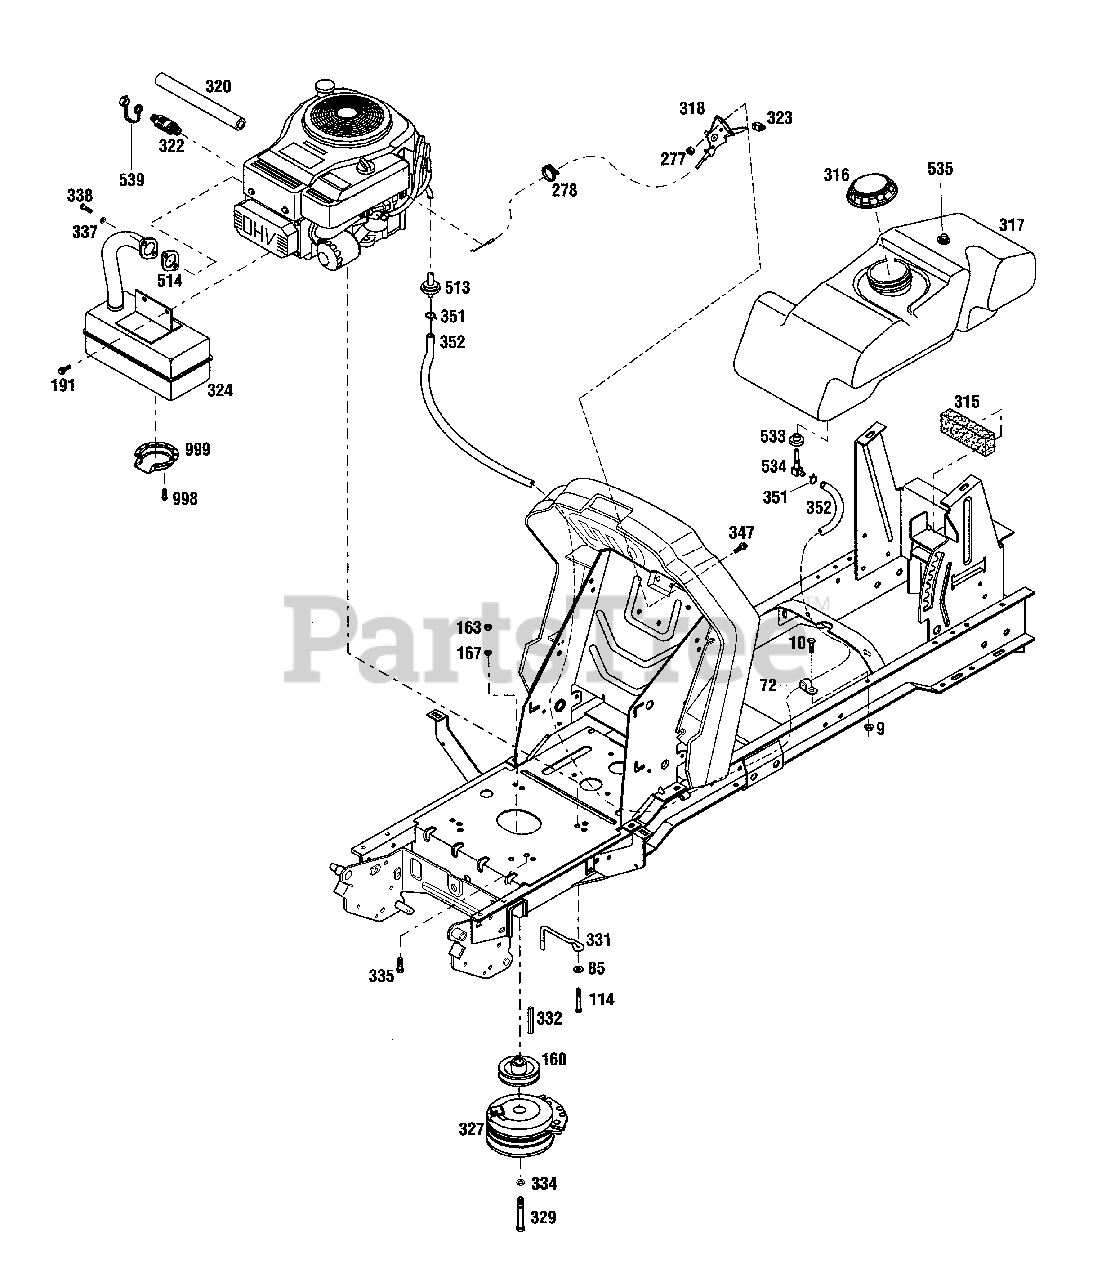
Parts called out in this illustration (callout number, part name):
9	Flange Nut, 5/16-18
10	Hex Head Screw, 5/16-18 x 3/4
85	Flat Washer, 3/8
114	Hex Head Screw, 3/8-16 x 1-1/2
160	Engine Sheave
163	Hex Nut, 3/8-16
167	Lockwasher 3/8
191	Flange Screw, 1/4-20 x 3/4
277	Keps Locknut, 10-24
278	Cable Tie
315	Fuel Tank Pad
316	Fuel Cap
317	Fuel Tank (Incl. Refs. 533, 534 & 535)
318	Throttle Choke Control (NLA)
320	Oil Drain Hose
322	Oil Valve Assembly (Incl. Ref. 539)
323	Control Knob
324	Muffler (Single Inlet)
327	Electric Clutch
329	Hex Head Screw, 7/16-20 x 3-1/4
331	Clutch Retainer
332	Square Key, 1/4 x 1-1/2
334	Spring Lock Washer, 7/16
335	Hex Head Screw, 3/8-16 x 1
337	Lock Washer, 5/16
338	Socket Cap Screw, 5/16-18 x 5/8
347	Machine Screw, 10-24 x 3/4
351	Hose Clamp
352	Fuel Line
513	Fuel Filter
514	Exhaust Gasket
533	Bushing
534	Fuel Tank Elbow
535	Fuel Tank Vent
539	Oil Drain Cap
998	Self Tapping Screw, #8-32 x 3/8
999	Muffler Deflector
